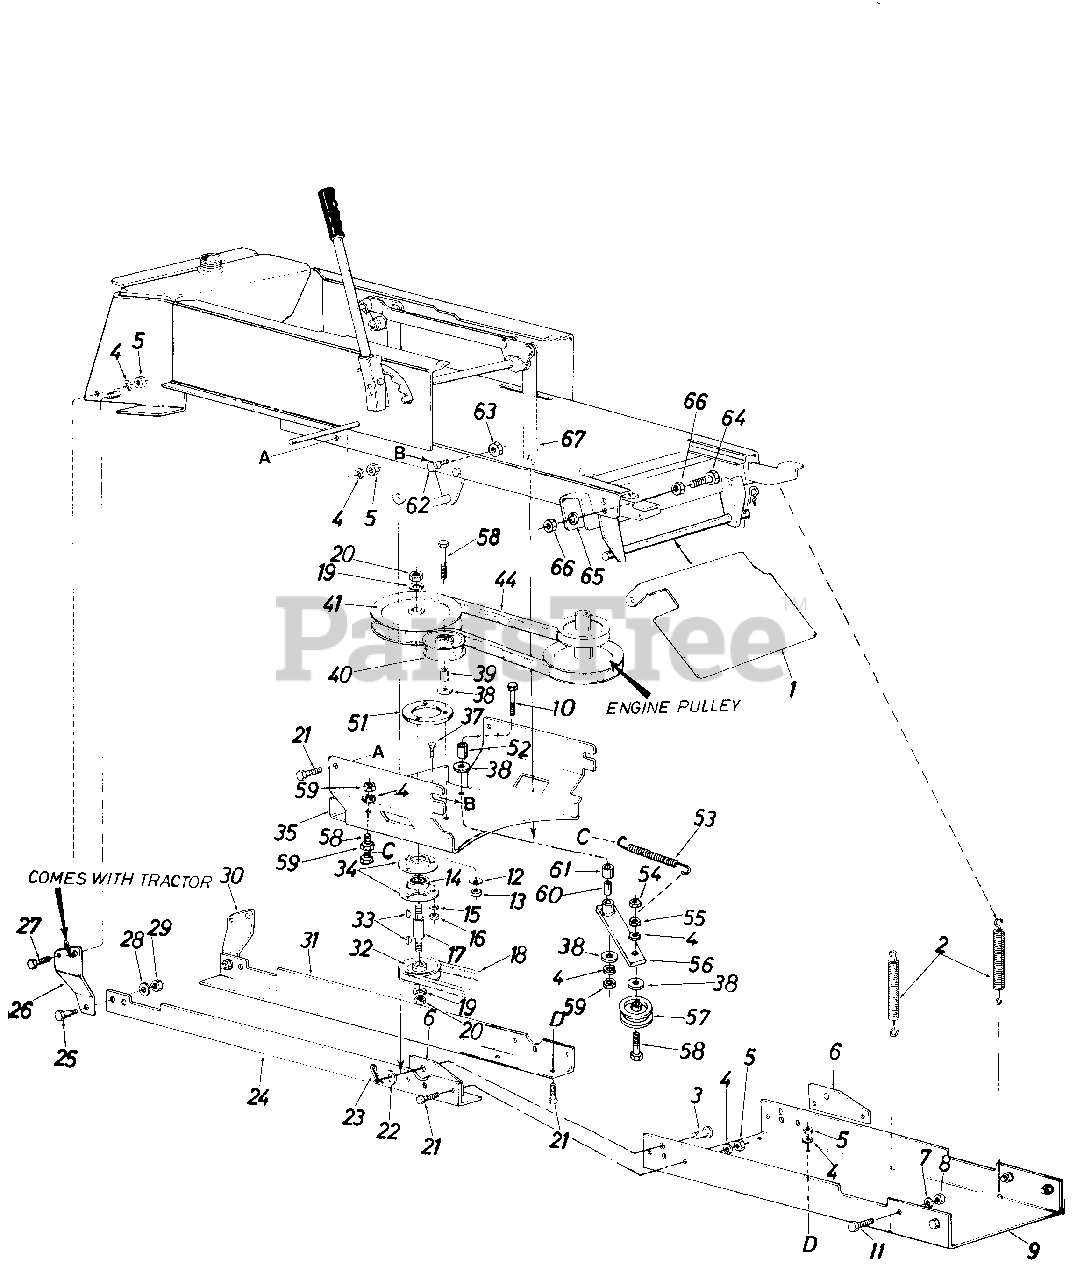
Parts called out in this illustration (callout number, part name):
1	Guide Bracket
2	Helper Spring
3	Clevis Pin
4	L.Wash. 3/8" I.D.*
5	Hex L.Nut 3/8-24 Thd.
6	Ataching Plate
7	L.Wash. 1/2" I.D.*
8	Hex L.Nut 1/2-20 Thd.
9	Front Support Channel
10	Hex Bolt 3/8-16 x 3.75" Lg.
11	Hex Bolt 1/2 20 x 1.25" Lg.*
12	L-Wash. 3/8" I.D.
13	Hex Jam Nut 3/8-16 Thd.
14	Ball Bearing
15	L.Wash. 5/16" I.D.*
16	Hex Nut 5/16-18 Thd.*
17	Spindle
18	"V" Belt
19	L.Wash. 5/8" I.D.*
20	Hex Jam Nut 5/8-11 Thd.
21	Hex Bolt 3/8-24 x 1.00" Lg.*
22	Flat Washer
23	Internal Coter Pin
28	Fl.Wash. 44" I.D. x 1.38" O.D. x .130
29	Hex L.Nut 7/16-24 Thd.
30	Rear Hanger Brkt.-L.H.
33	#6 Hi-Pro Key 3/16 x 5/8" Dia.
34	Bearing Housing
35	Supporting Bracket
37	Hex Sems Bolt 5/16-18 x 1.00" 0 0 Lg.*
38	Fl.Wash. .38" I.D. x 1.00" O.D. x .135
39	Spacer.38" I.D. x .62" O.D.
40	Fl. ldler Pulley
41	Upper Drive Pulley
44	"V" Belt
53	Extension Spring .54" O.D. x 4.75" Lg.
54	Hex Cent. L.Nut 3/8-16 Thd.
55	Hex Jam Nut 3/8-16 Thd.
56	Idler Arm Ass'y.
57	Idler Pulley
58	Hex Bolt 3/8-16 x 2.25" Lg.
59	Hex Jam Nut 3/8-16 Thd.
60	Spacer 377" I.D. x .60" O.D. x .830" Lg.
61	Spacer.380" I.D. x .630" O.D. x 565" Lg.
62	Shoulder Bolt .498 Dia. x .340
63	Hex Cent. L.Nut 3/8-16 Thd.
64	Hex Bolt 1/4-28 x 1.50" Lg.
65	L.Wash. 1/4" I.D.
66	Hex Nut 1/4-28 Thd.
